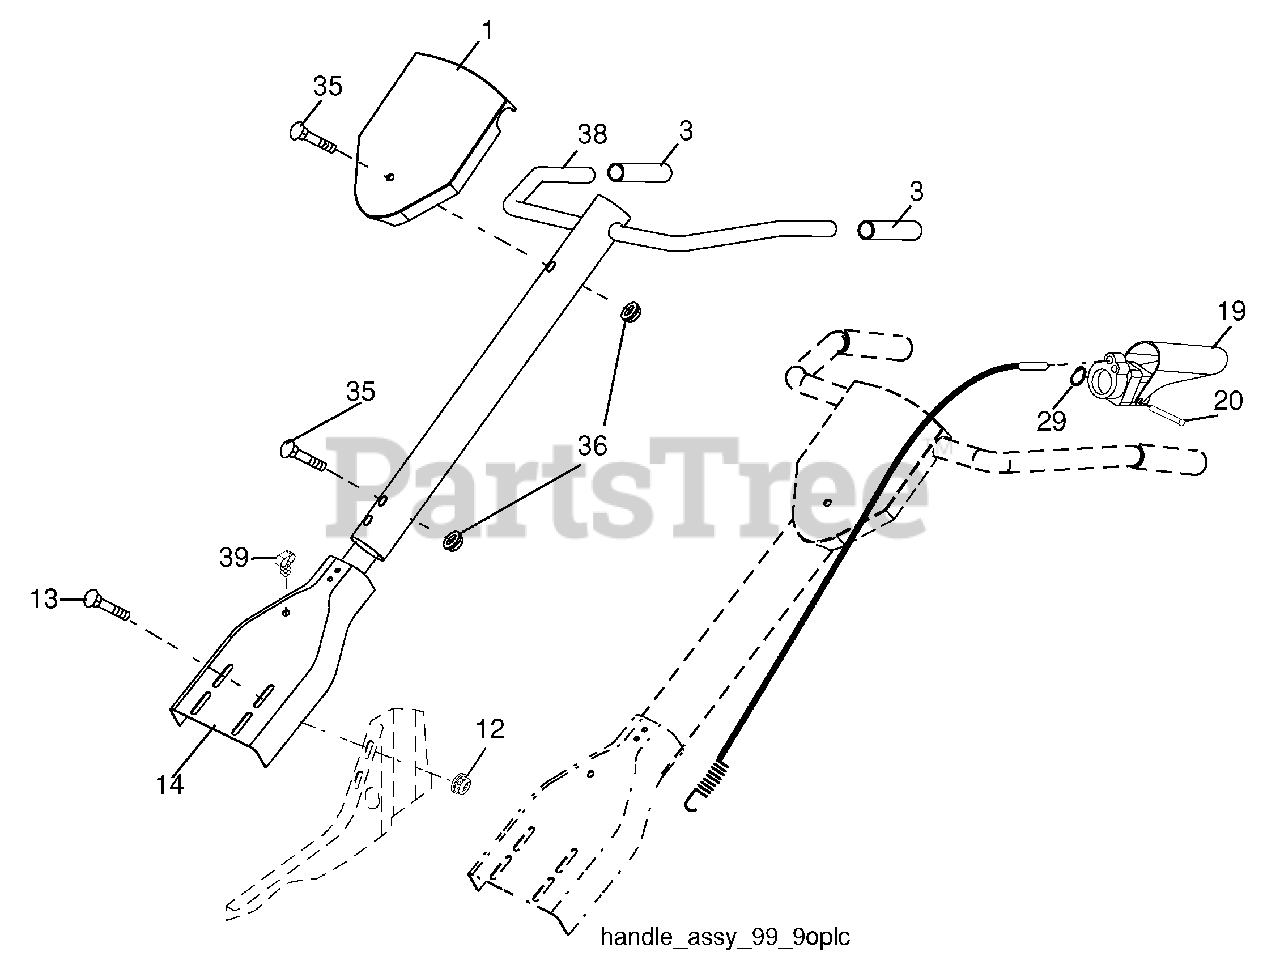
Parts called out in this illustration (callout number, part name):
1	Panel, Control
3	Grip, Handle
12	Nut, Flange
13	Bolt, Carriage 5/16-18 x 3/4
14	Assembly, Panel and Tube
19	Lever, Control, Tine
20	Pin, Pivot
29	Retainer, Ring
35	Bolt 5/16-18 x 2-1/2
36	Locknut, Flange 5/16-18 unc
38	Assembly, Handle Column
39	Clip
